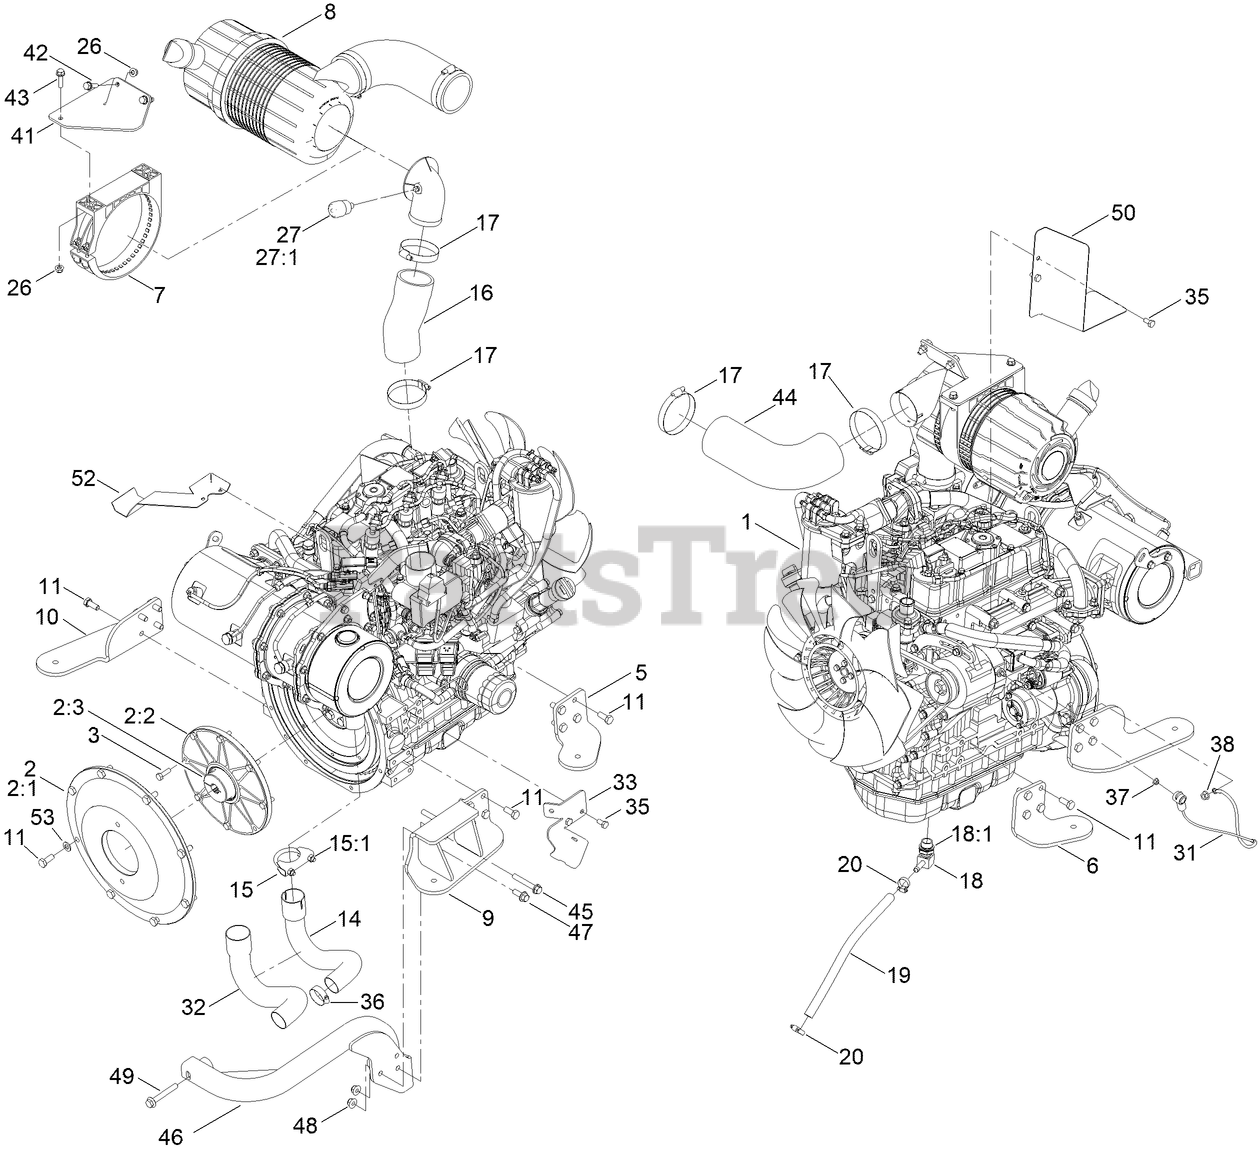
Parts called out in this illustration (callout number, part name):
1	ENGINE-YANMAR, 3TNV88C-DTR
2	KIT-DRIVE COUPLER
2:1	PLATE- MOUNTING, PUMP
2:2	FLANGE-FLYWHEEL
2:3	HUB-PUMP
3	SCREW-HH
5	MOUNT-ENGINE
6	MOUNT-ENGINE
7	STRAP-CLEANER, AIR
8	AIR CLEANER ASM
9	MOUNT-ENGINE [BLACK]
10	MOUNT-ENGINE
11	SCREW-HH
14	PIPE-EXHAUST
15	CLAMP-MUFFLER
15:1	NUT-JAM
16	HOSE-AIR,INLET
17	CLAMP-HOSE
18	FITTING-BARBED-90
18:1	WASHER-SEAL, BONDED
19	HOSE-OVERFLOW, RADIATOR
20	CLAMP-HOSE
26	NUT-HF, NI
27	INDICATOR
27:1	ADAPTER-INDICATOR
31	HARNESS-WIRE
32	SLEEVE-EXHAUST
33	BRACKET-GUARD
35	SCREW-HH
36	CLAMP-HOSE
37	NUT-HF
38	NUT-HF
41	BRACKET-FILTER,AIR
42	SCREW-HHF
43	SCREW-HHF
44	HOSE-INTAKE
45	SCREW-HFH
46	SUPPORT-PUMP [BLACK]
47	SCREW-HHF
48	NUT-HF, NI
49	SCREW-HHF
50	BRACKET-DIVERTER, AIR
52	SHIELD-HEAT
53	WASHER-FLAT
